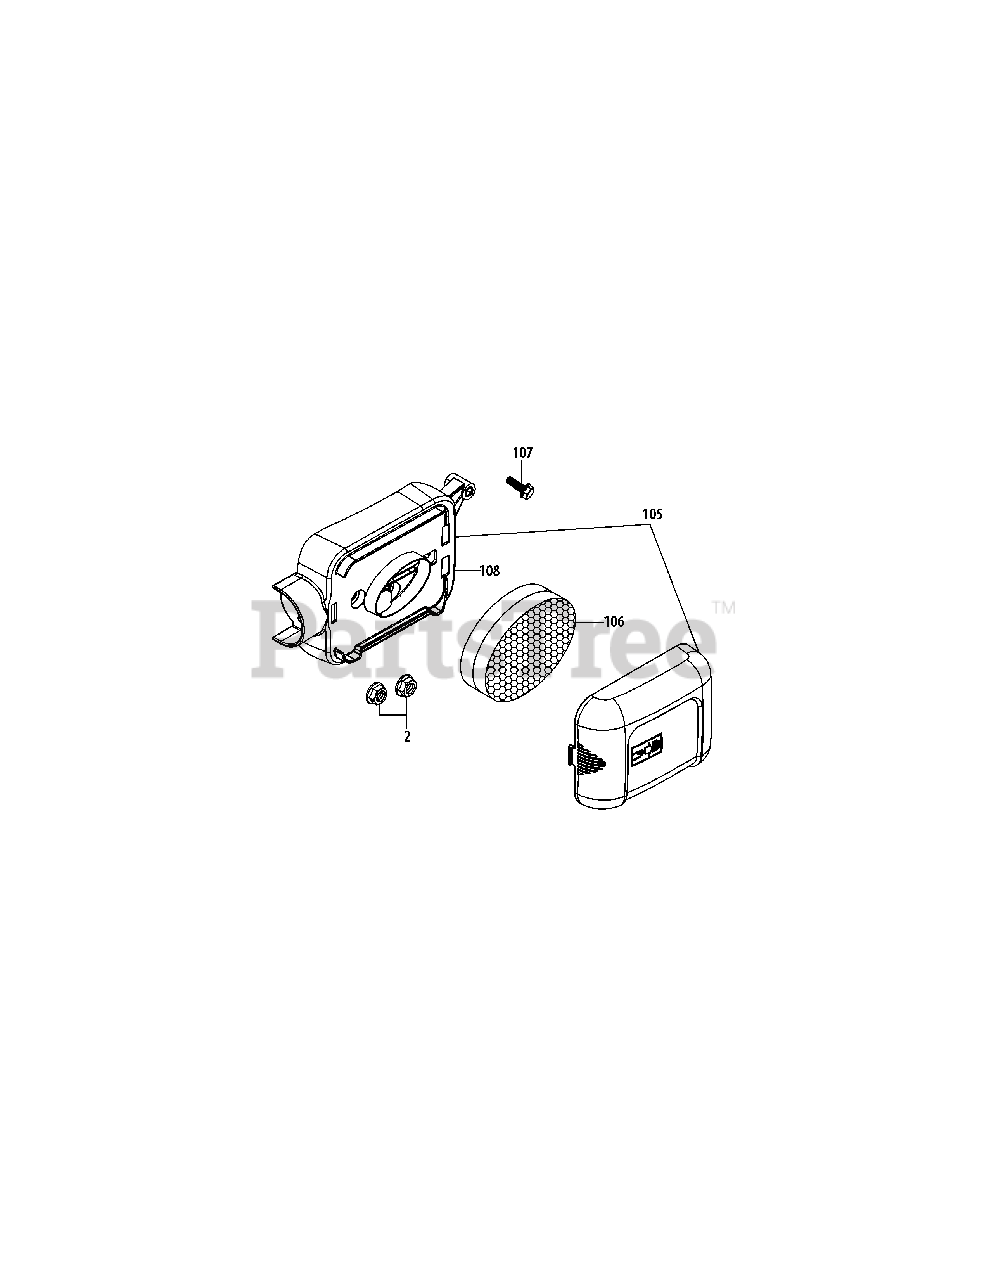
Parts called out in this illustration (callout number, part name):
2	Nut M6 X 10 Mm
105	Air Cleaner Housing Assy (Incl. 108)
106	Air Filter Element, Oval
107	Bolt M6×30
108	Air Filter Base
